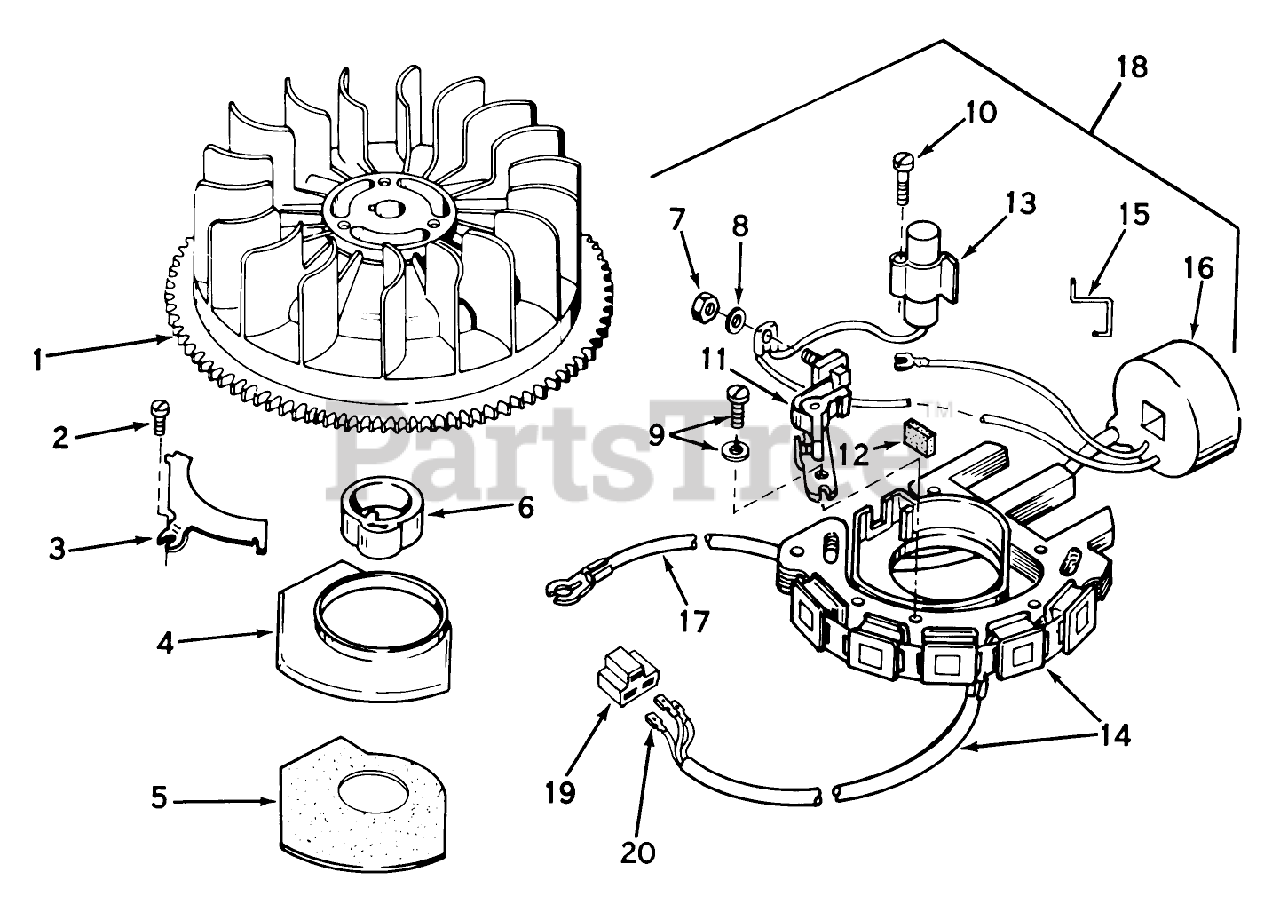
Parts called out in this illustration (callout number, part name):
1	Flywheel
2	Screw, Dust Cover
3	Clamp, Dust Cover
4	Cover, Dust
5	63563A GIL MWR ATTC
6	Cam, Breaker
7	DECAL
8	Washer
9	Breaker Screw
10	Condenser Screw
11	Contact Assy., Breaker
12	Felt,Cam Wiper
13	Condenser
14	Stator Core Generating Coils (Incl. Nos. 19 20)
15	Clip, Coil
17	Wire, Lead
18	Stator Plate Assy. (Incl. Nos. 2 thru 5, 7 thru 17, 19 20)
19	Connector, Pyramid
20	Terminal
